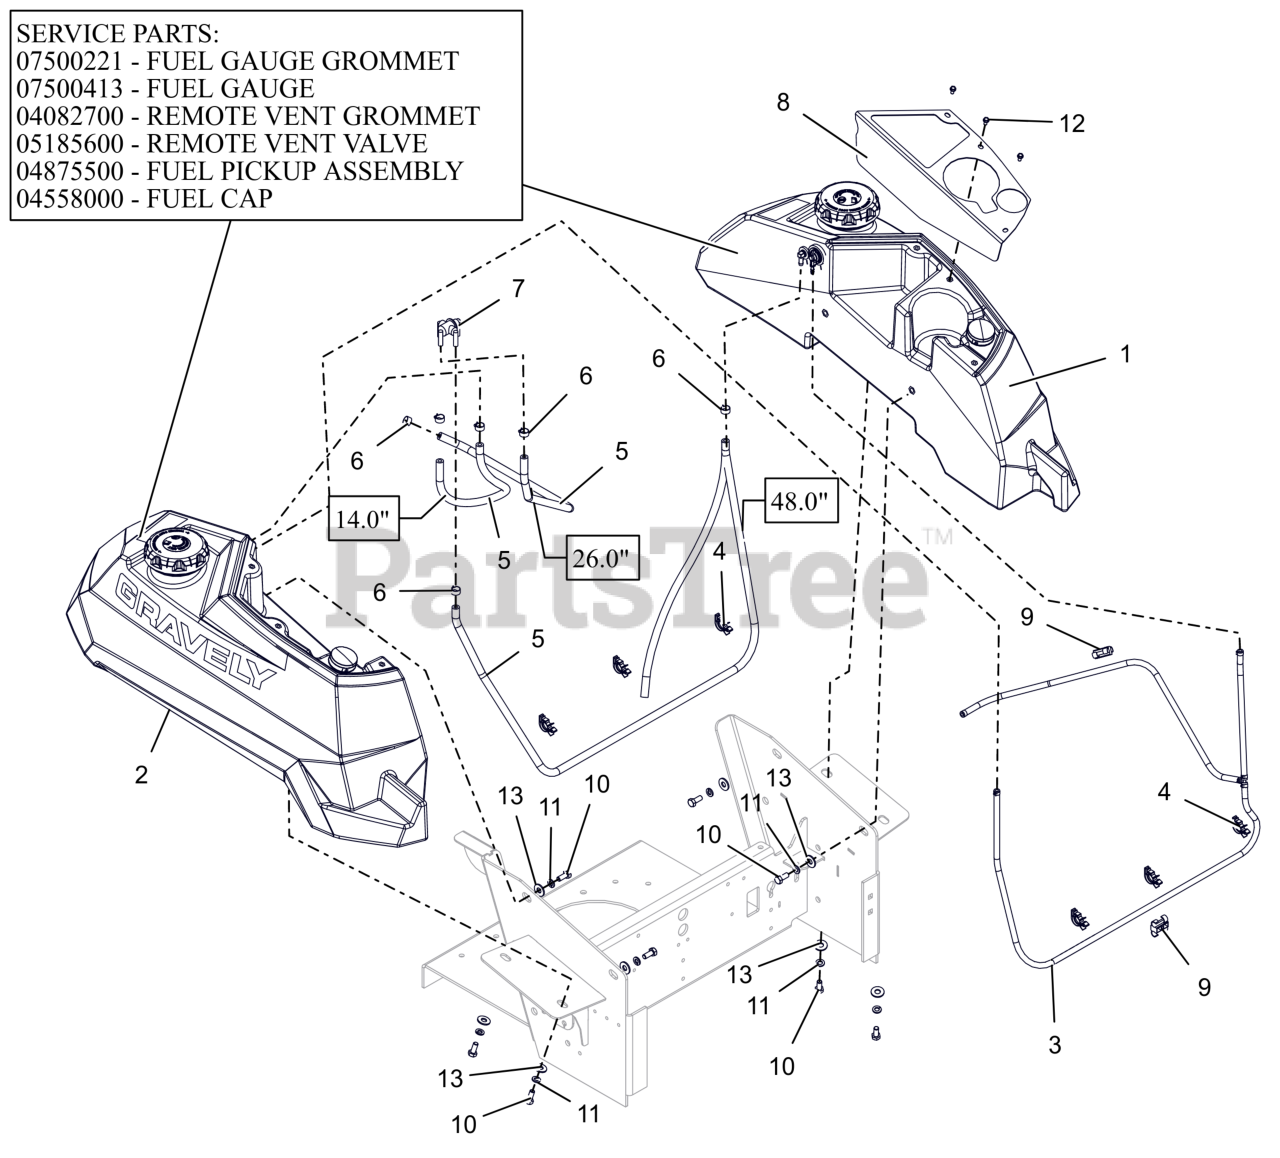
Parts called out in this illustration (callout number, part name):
1	ASM, LH - PT100 FUEL TANK
1	GROMMET, FUEL GAUGE
1	GAUGE, REMOTE SEALED FUEL
1	GROMMET, REMOTE VENT NITRILE
1	VALVE, COMBINATION VENT 3/16
1	ASSM,LRG TANK FUEL PICKUP LINE
1	CAP, FUEL VENTIN AUTOLOCK
2	ASM, RH - PT100 FUEL TANK
2	GROMMET, FUEL GAUGE
2	GAUGE, REMOTE SEALED FUEL
2	GROMMET, REMOTE VENT NITRILE
2	VALVE, COMBINATION VENT 3/16
2	ASSM,LRG TANK FUEL PICKUP LINE
2	CAP, FUEL VENTIN AUTOLOCK
3	ASM, VAPOR LINE
4	WIRE CLIP
5	HOSE, .25 LOW-PERM BULK GAS
6	CLAMP, FUEL LINE
7	VALVE, FUEL
8	PT100 CUPHOLDER PANEL - RED
9	CLIP, T, .38-.50
10	BLT,HEX .31-18X.75 G5 ZCC
11	WSHR,LK-REG .312X.078 ZCC
12	SCR-MCH 10-24X.38 HWHSTAINLESS
13	WSHR,FLT .375X.875X.083 ZCC
